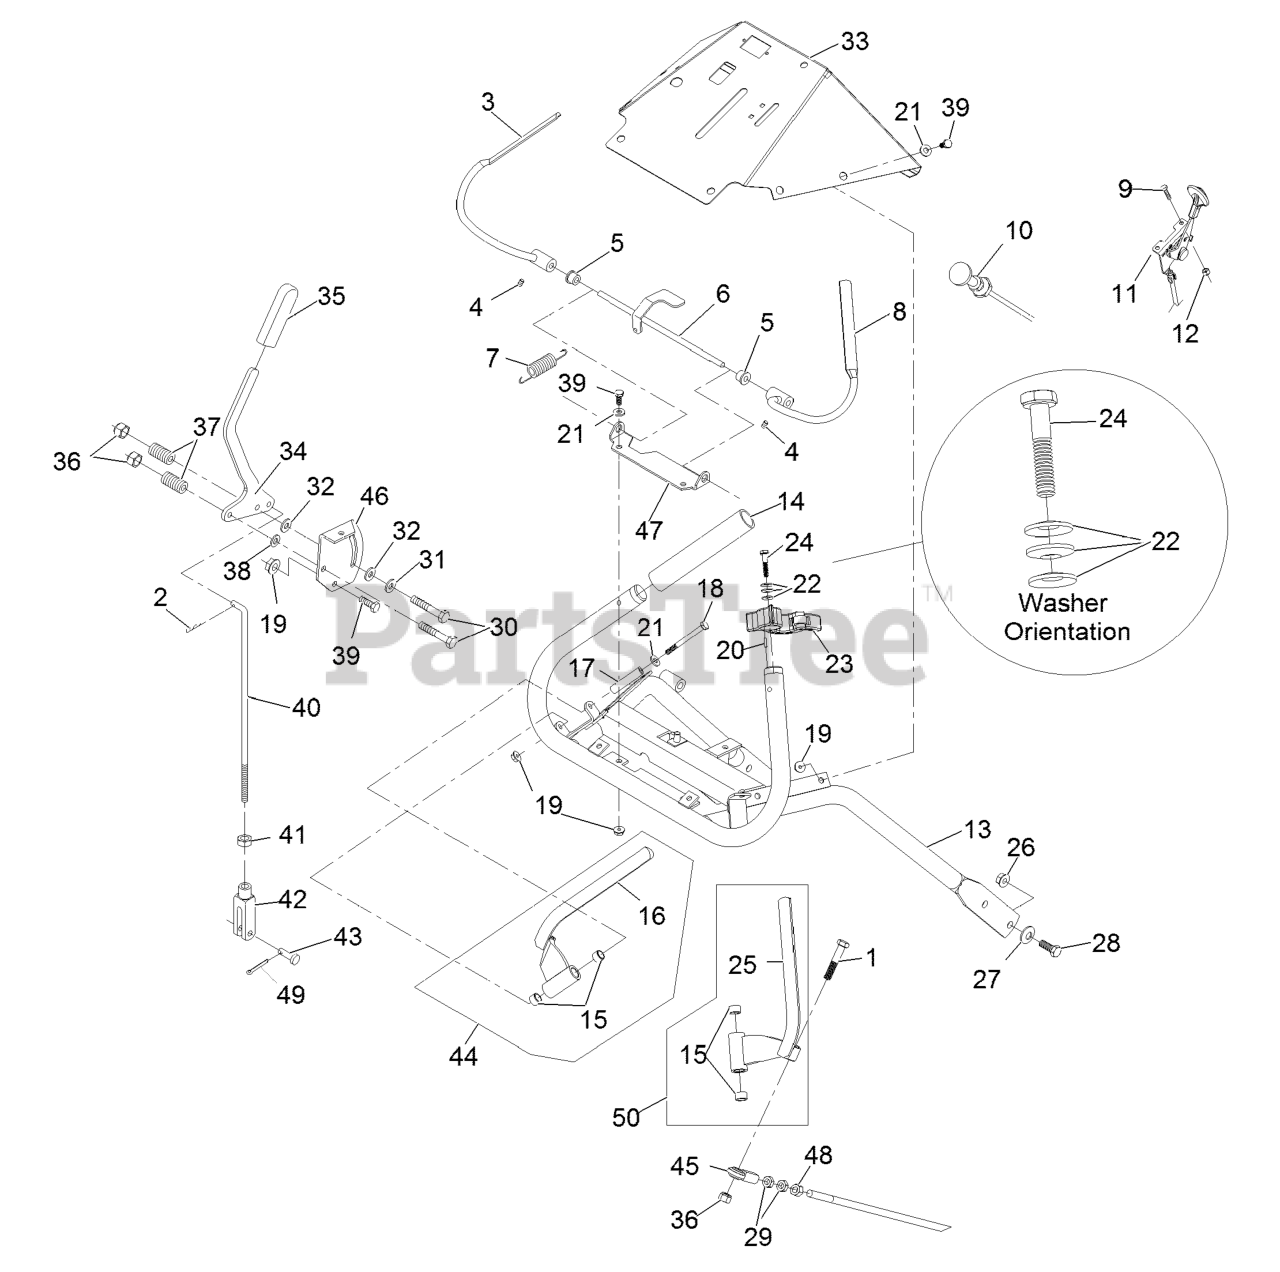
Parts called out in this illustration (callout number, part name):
1	SCREW-HH
2	PIN-COTTER
3	WLD,LH OPC LEVER
4	SCREW-SET
5	BUSHING-NYLON
6	WLD,OPC LEVER AXLE
7	SPRING-EXTENSION
8	WLD,RH OPC LEVER
9	BOLT-CARR
10	CONTROL-CHOKE, PUSH / PUL
11	CONTROL, THROTTLE
12	NUT-LOCK, NI
13	WLD,TTH ECS HANDLE
14	GRIP-BAR, HANDLE
15	BUSHING-SLEEVE
16	WLD,LH DRIVE LEVER
17	BUSHING-LEVER, DRIVE
18	SCREW-HH
21	WASHER-FLAT
22	WASHER-SPRING
23	ASM,LATCH RH THUMB
24	SCREW-HH
25	WLD,RH DRIVE LEVER
26	NUT-HHF, WHIZ
27	WASHER-BELLEVILLE
28	SCREW-HH
29	NUT-HJ
30	SCREW-HH
31	WASHER-FRICTION
32	WASHER-FRICTION
33	KIT, TT ECS CONSOLE
34	LEVER, SHIFT W/GRIP
35	GRIP-HANDLE, STEERING
36	NUT-LOCK, NI
37	SPRING-COMPRESSION
38	WASHER-PLAIN
39	SCREW-HH
40	ROD,SPEED CONTROL
41	NUT-JAM
42	YOKE-ADJUSTABLE
43	PIN-CLEVIS
44	DRIVE LEVER-ASM, LH
45	JOINT-BALL, END
46	BRACKET,SHIFTER SLIDE (PL
47	BRACKET,OPC AXLE
48	NUT-HEX
49	PIN-COTTER
50	DRIVE LEVER-ASM, RH
